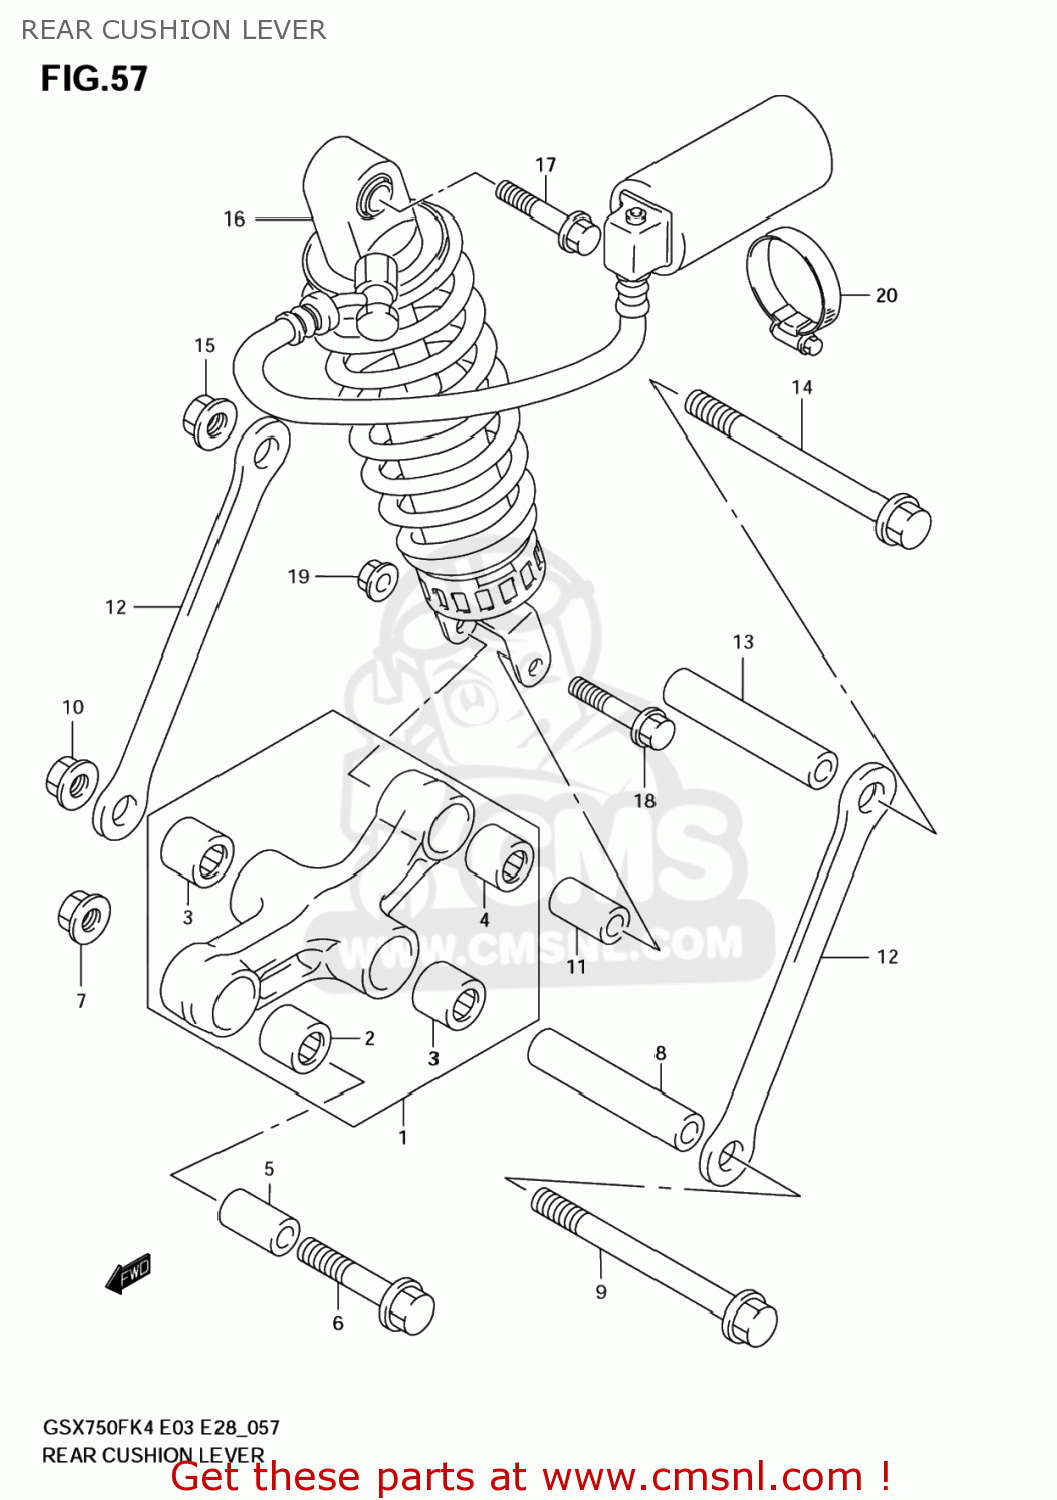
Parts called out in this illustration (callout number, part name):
1	LEVER SET,RR CUSHION
2	BEARING(20X27X30)
3	BEARING(20X27X23.5)
4	BEARING(17X24X26)
5	SPACER(14X20X34)
6	BOLT(14X62)
7	NUT
8	SPACER,RR CUSHION ROD
9	SHAFT,RR CUSHION ROD
10	NUT
11	SPACER,RR CUSHION LEVER
12	ROD,RR CUSHION
13	SPACER,RR CUSHION ROD
14	SHAFT,RR CUSHION ROD
15	NUT
16	ABSORBER ASSY,RR SHOCK
17	BOLT(10X52)
18	BOLT(10X44)
19	NUT
20	CLAMP
